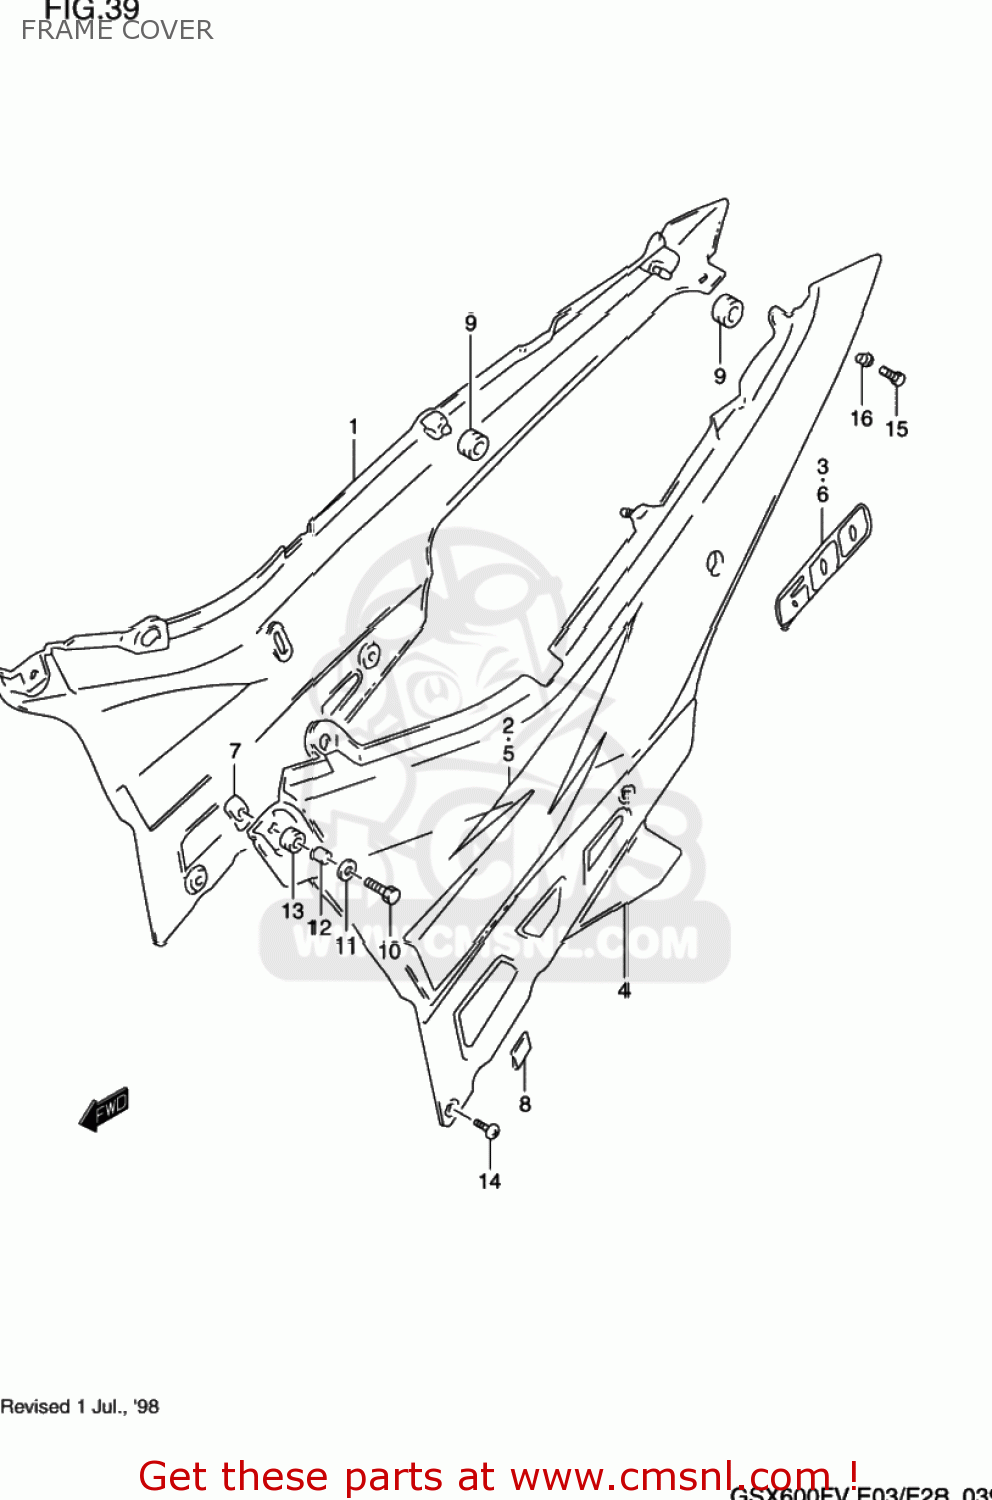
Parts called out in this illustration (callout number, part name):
1	COVER COMP,FRAME,RIGHT
2	TAPE,FRAME COVER,RIGHT
3	EMBLEM,FRAME COVER
4	COVER,FRAME,L
5	TAPE,FRAME COVER,LEFT
6	EMBLEM,FRAME COVER
7	PLATE,FRAME COVER
8	CUSHION,FRAME COVER
9	CUSHION
10	SCREW(6X20)
11	WASHER(6.5X18X1.6)
12	SPACER(6.5X9X9)
13	CUSHION
14	SCREW(5X15.3)
19	SCREW 5X12
20	WASHER
